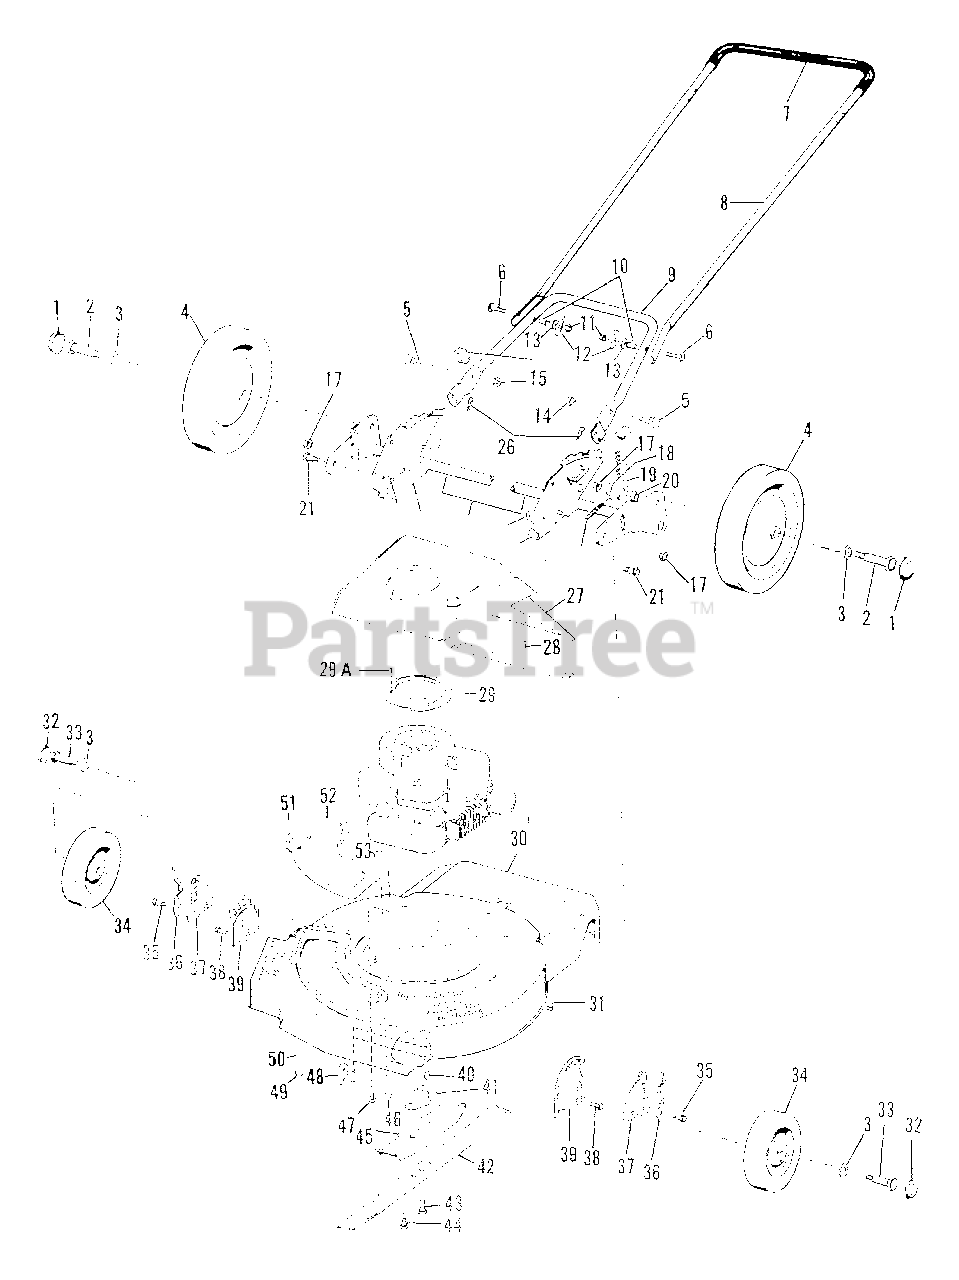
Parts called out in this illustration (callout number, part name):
1	CAP, Hub (Rear)
2	BOLT, Wheel (Rear)
3	WASHER, Spring
4	WHEEL, 10" (Rear)
5	BOLT, Handle Latch
6	BOLT, Curved Head
7	TUBING, Handle
8	HANDLE, Upper
9	HANDLE, Lower
10	EYELET, Handle
11	NUT, Hex, 5/16-18
13	WASHER, Flat, 1/4
14	NUT, Hex, 5/16-18
15	NUT, Handle Latch
16	LATCH, Handle
17	NUT, Hex, 3/8-16
18	WASHER, Flat, 5/16
19	ADJUSTER, Height (Rear)
21	BOLT, Hex, Shoulder
22	SPRING, Height Adjust (Rear)
23	BRACKET, L.H.
24	PLATE & TUBE
25	BRACKET, R.H.
26	CLIP, Spring
28	SCREW, Hex, 12-24 x 1/2
30	HOUSING, 21"
31	SCREW, Hex, 1/4-20 x 3/8
32	CAP, Hub (Front)
33	BOLT, Wheel (Front)
34	WHEEL, 6" (Front)
35	BOLT, Hex, Shoulder
36	SPRING, Height Adjust (Front)
37	ADJUSTER, Height (Front)
38	SCREW, Hex Cap, 3/8-16 x 5/8
39	PLATE, Adjusting
40	KEY, Woodruff, #6
41	ADAPTER, Blade
43	SCREW, Hex Cap, 3/8-24 x 1-1/2
44	SCREW, Hex, 5/16-18 x 1
45	STIFFENER, Blade
46	SPEED NUT, Special
47	BOLT, Engine Mounting, 3/8-16 x 1
48	NUT, Twin Pilot
49	NUT, Hex, 1/4-20
51	SCREW, Special
52	PLATE, cover
53	SCREW, Thumb, 1/4-20 x 5/8
